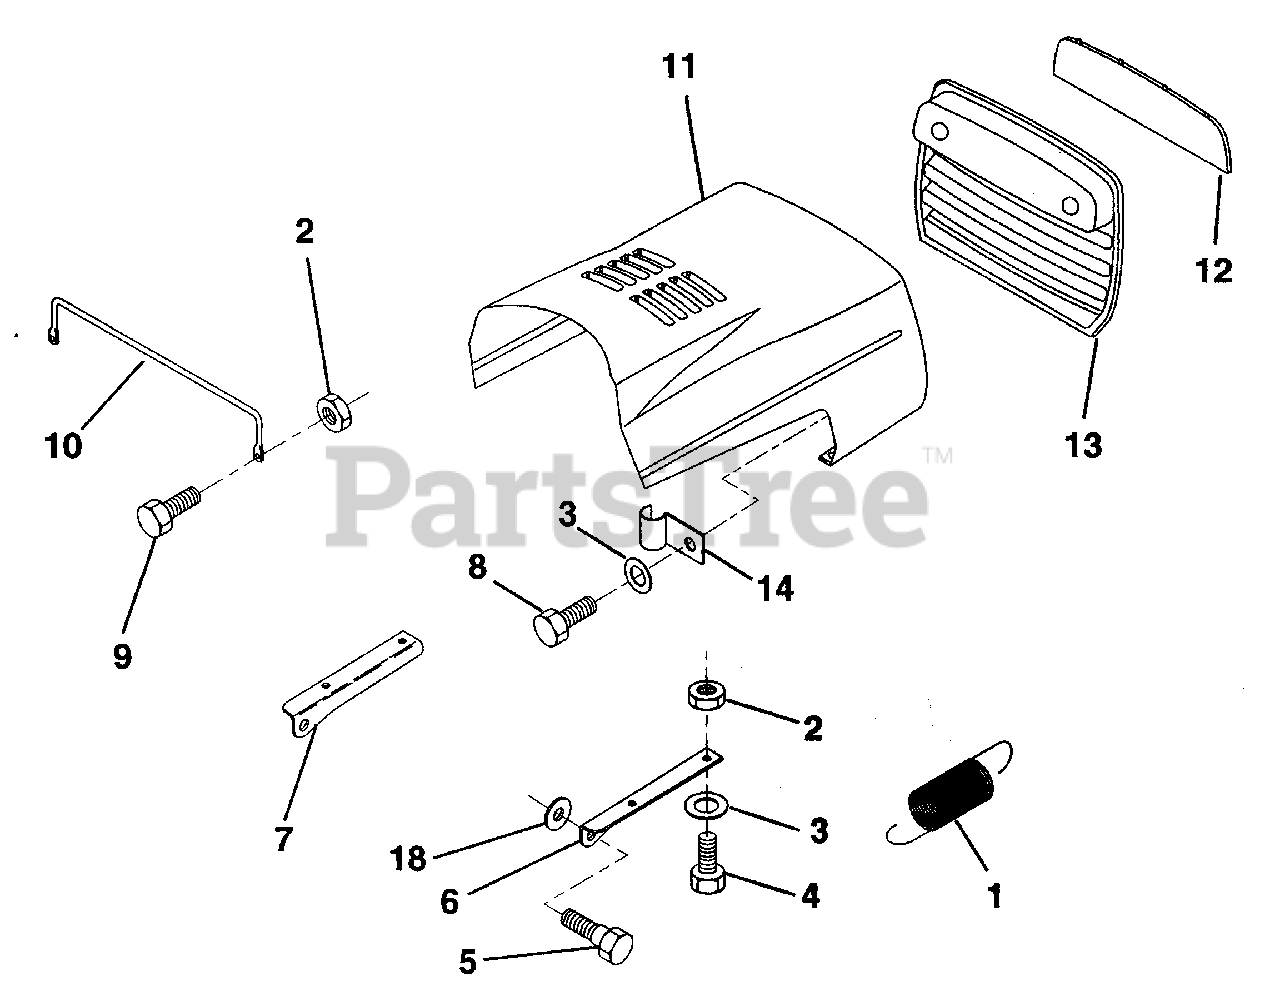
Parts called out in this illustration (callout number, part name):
1	Spring, Extension (AYP part number)
2	Nut, Hex, Keps 1/4-20 UNC (AYP part number)
3	Washer 9/32 x 5/8 x 16 Gauge (AYP part number)
4	Bolt, Hex, Fin 1/4-20 UNC x 5/8 Grade 5 (AYP part number)
5	Bolt, Shoulder (AYP part number)
6	Bracket, Hood, RH (AYP part number)
7	Bracket, Hood, LH (AYP part number)
8	Screw, Hex, Fin #13-16 Hi-Lo x 5/8 (AYP part number)
9	Bolt, Hex, Fin 1/4-20 x 3/4 Grade 5 (AYP part number)
10	Brace, Hood (AYP part number)
11	Hood (AYP part number)
12	Lens (AYP part number)
13	Grill (AYP part number)
14	Clip, Fuel (AYP part number)
18	Washer 11/32 x 11/16 x 16 Gauge (AYP part number)
